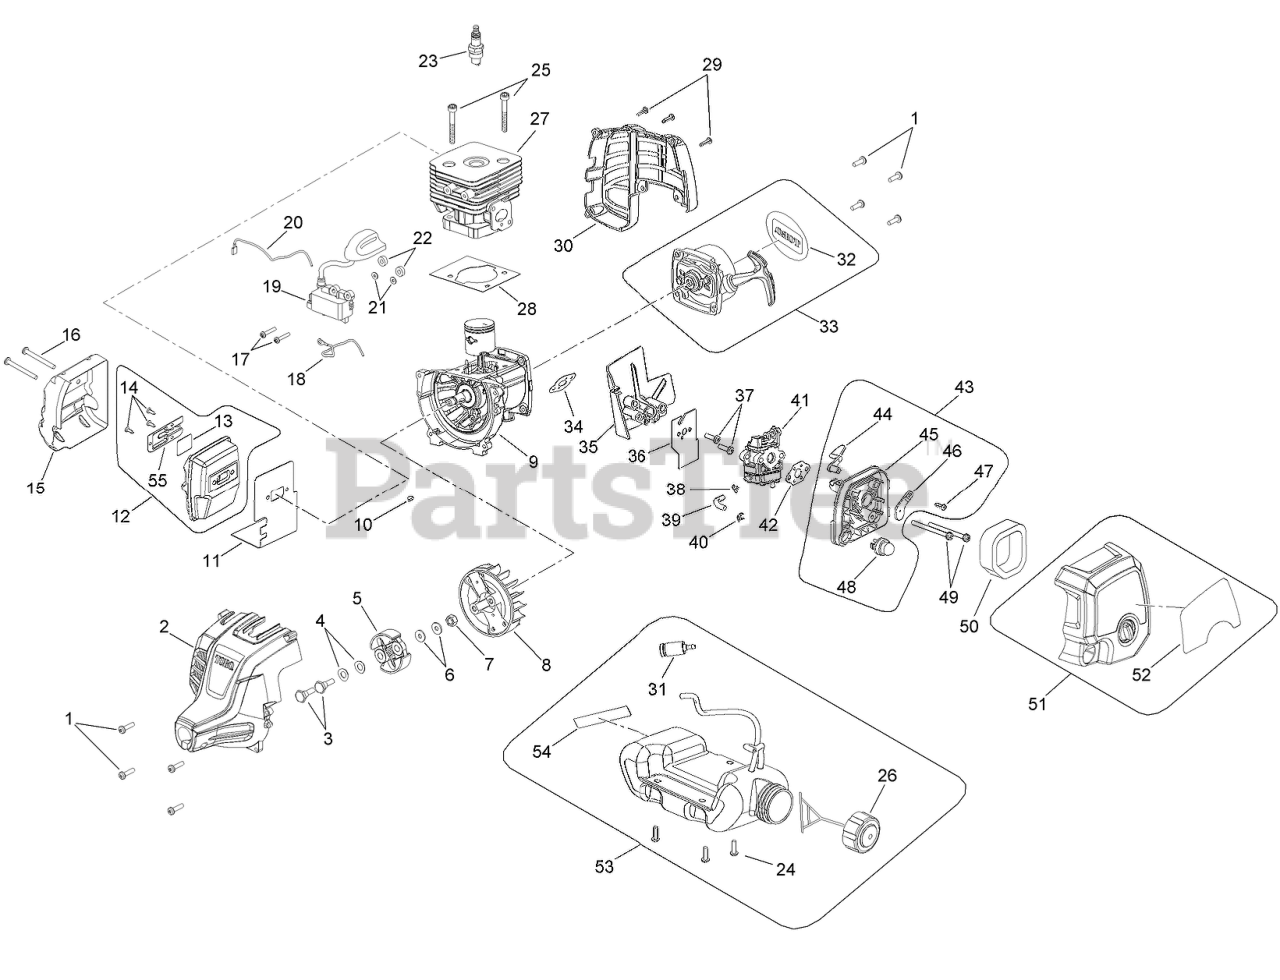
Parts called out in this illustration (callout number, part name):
1	SCREW-PH
2	HOUSING-ENGINE, FRONT
3	SCREW-CLUTCH
4	WASHER-CURVED
5	CLUTCH ASM
7	NUT-ROTOR
9	CRANKCASE ASM
10	KEY-WOODRUFF
11	GASKET-MUFFLER
12	MUFFLER ASM
14	SCREW-PH
15	SHIELD-HEAT
16	SCREW-PH
17	SCREW AND WASHER
18	WIRE-LEAD, RED
19	COIL BOOT ASM
20	WIRE-LEAD, BLACK
23	SPARK PLUG
24	T25 TORX PAN HEAD
25	SCREW-SOCKET HEAD
26	CAP-FUEL
27	CYLINDER
30	HOUSING-ENGINE, REAR
31	FILTER-FUEL
32	PLATE-LOGO
33	RECOIL STARTER AND STARTER CUP ASM
34	GASKET-HEAT DAM
35	HEAT DAM
37	SCREW AND WASHER
38	CLIP-HOSE
39	FUEL LINE 45MM
40	CLIP-HOSE
41	CARBURETOR ASM
42	GASKET-CARBURETOR
43	FILTER HOUSING ASM
44	LEVER-CHOKE
45	PLATE-CARBURETOR
46	PLATE-CHOKE
47	SCREW-PH
48	PRIMER ASM
49	T20 TORX CAP SOC HD
50	ELEMENT-FILTER, AIR
51	COVER ASM
52	DECAL-START
53	FUEL TANK AND CAP ASM
54	COMBUSTION WARNING LABEL
55	COVER-TRIMMER
